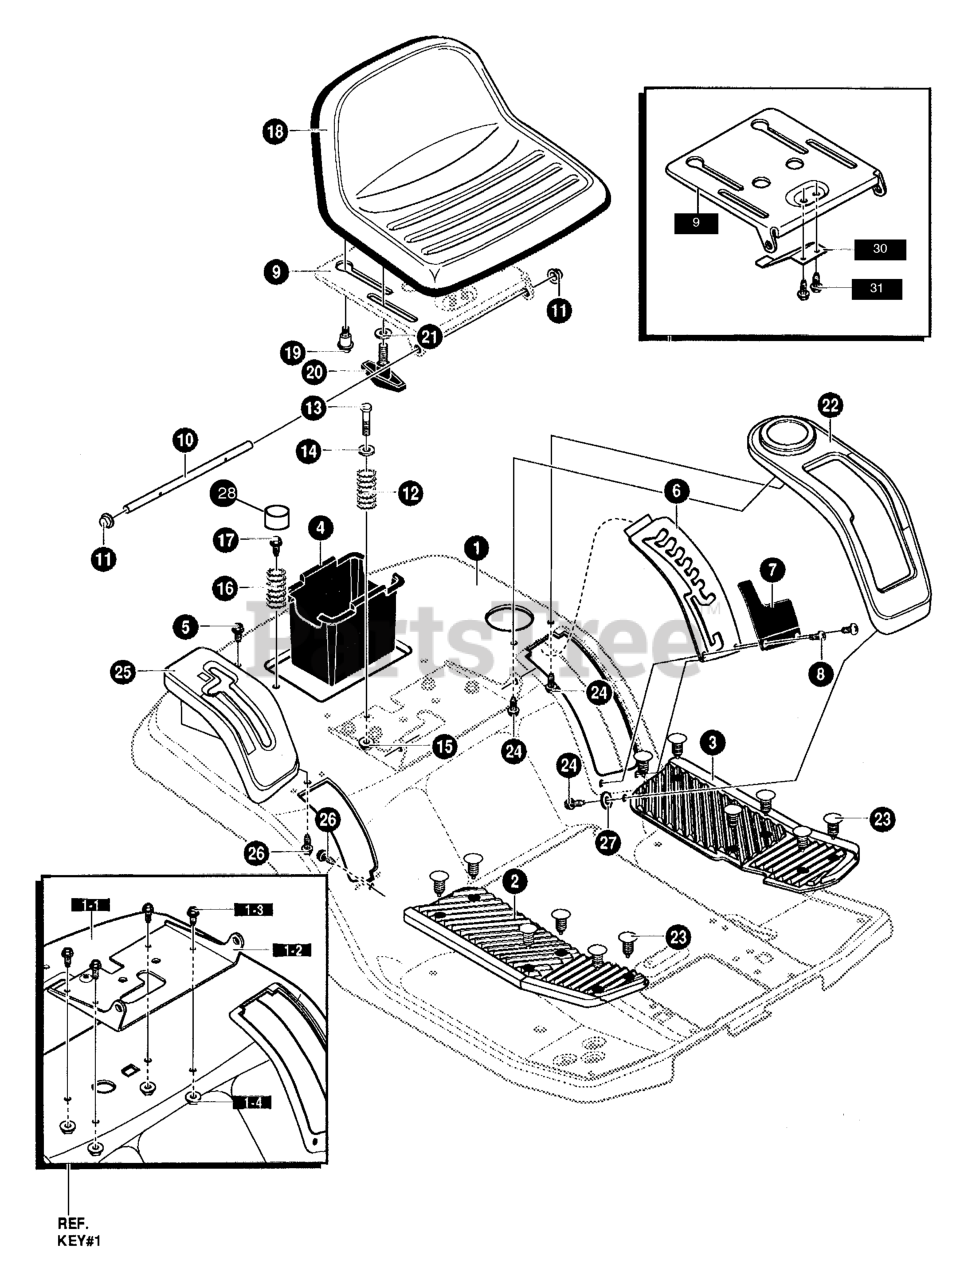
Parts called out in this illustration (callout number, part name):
1	LARGE SEAT DECK
1-1	SEAT DECK, LARGE
1-2	BRACKET, PIVOT SEAT
1-3	SCREW, 5/16-18 x 0.75
1-4	NUT, 5/16- 18
2	FOOT REST PAD RH
3	FOOT REST PAD LH
4	CONTAINER, BATTERY
5	SCREW 1/4-20X.63
6	PLATE, LIFT DETENT
7	COVER, LIFT DETENT
9	SUPPORT, SEAT
10	HINGE SEAT PIVOT
11	NUT, PUSH CAP
12	SPRING, COMPRESS
13	BOLT, SHOULDER 1/4-20
14	WASHER CUP
15	NUT, 1/4- 20
16	SPRING, COMPRESS
17	SCREW 5/16- 18X.75
19	BOLT, SHOULDER 5/16- 18
20	BOLT, WING 5/16- 18X.50
21	Washer
22	COVER, DETENT PLATE
23	FASTENER, RATCHET
24	SCREW, 1/4- 15X.44/.53
25	COVER, HAND/FOOT, HYDRO
26	SCREW, 1/4- 15X.44/.53
27	FLATWASHER
30	SPRING, LEAF
31	SCREW, 1/4-20X.50
